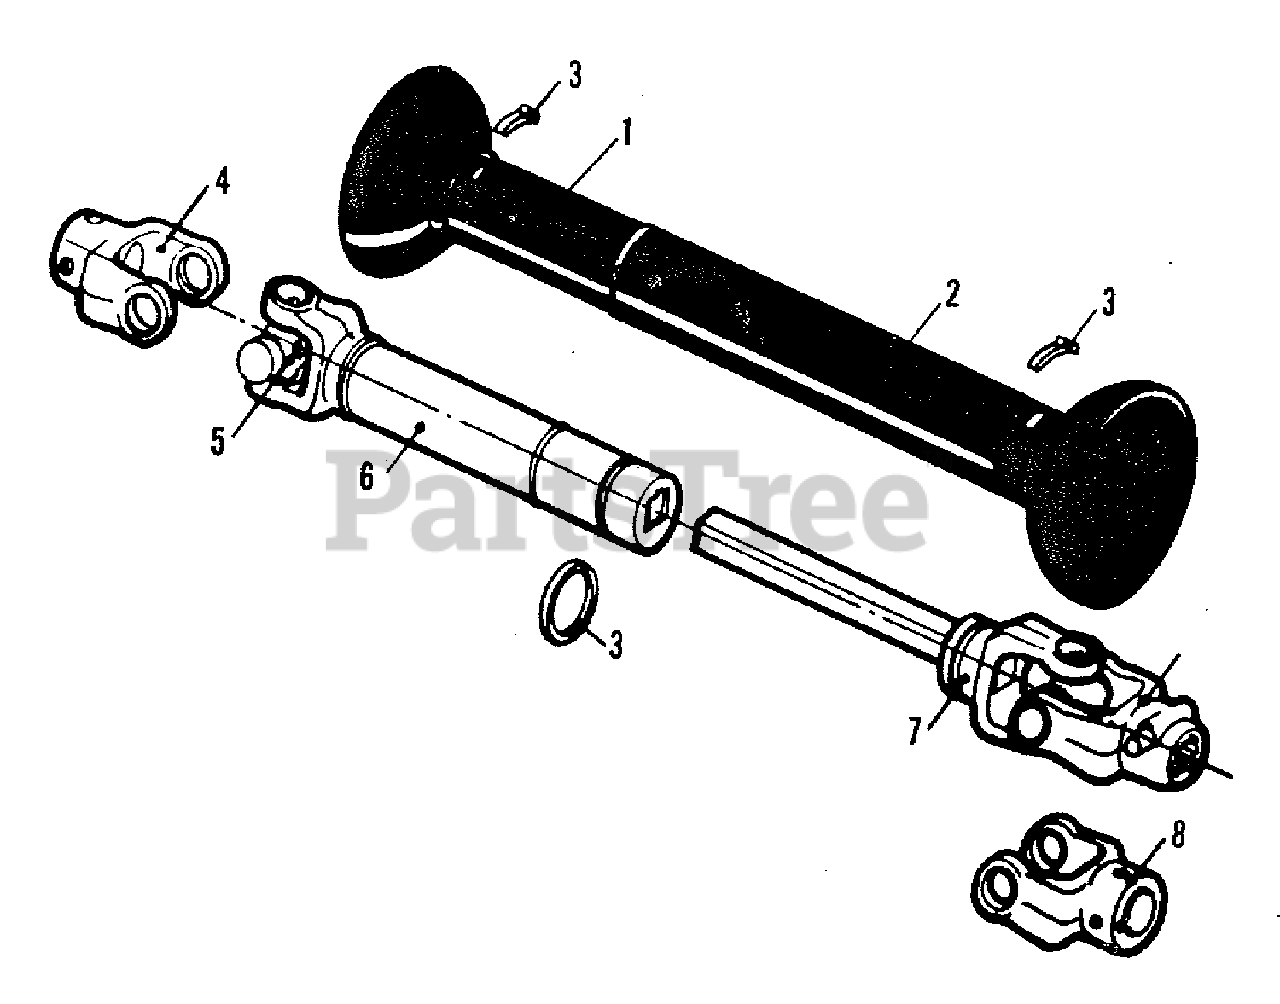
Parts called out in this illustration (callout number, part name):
1	SHIELD, Inner, Front
2	SHIELD, Outer, Front
3	BEARING KIT, Shield
4	YOKE, End, 1-1/4" Bore, 5/16" Cross Hole
5	CROSS KIT, U-Joint
6	SLEEVE ASSEMBLY, P.T.O. Front
7	SHAFT ASSEMBLY, PTO, Front
8	YOKE, 1-1/4" Bore (w/ 3/8NC SETSCREWS)
